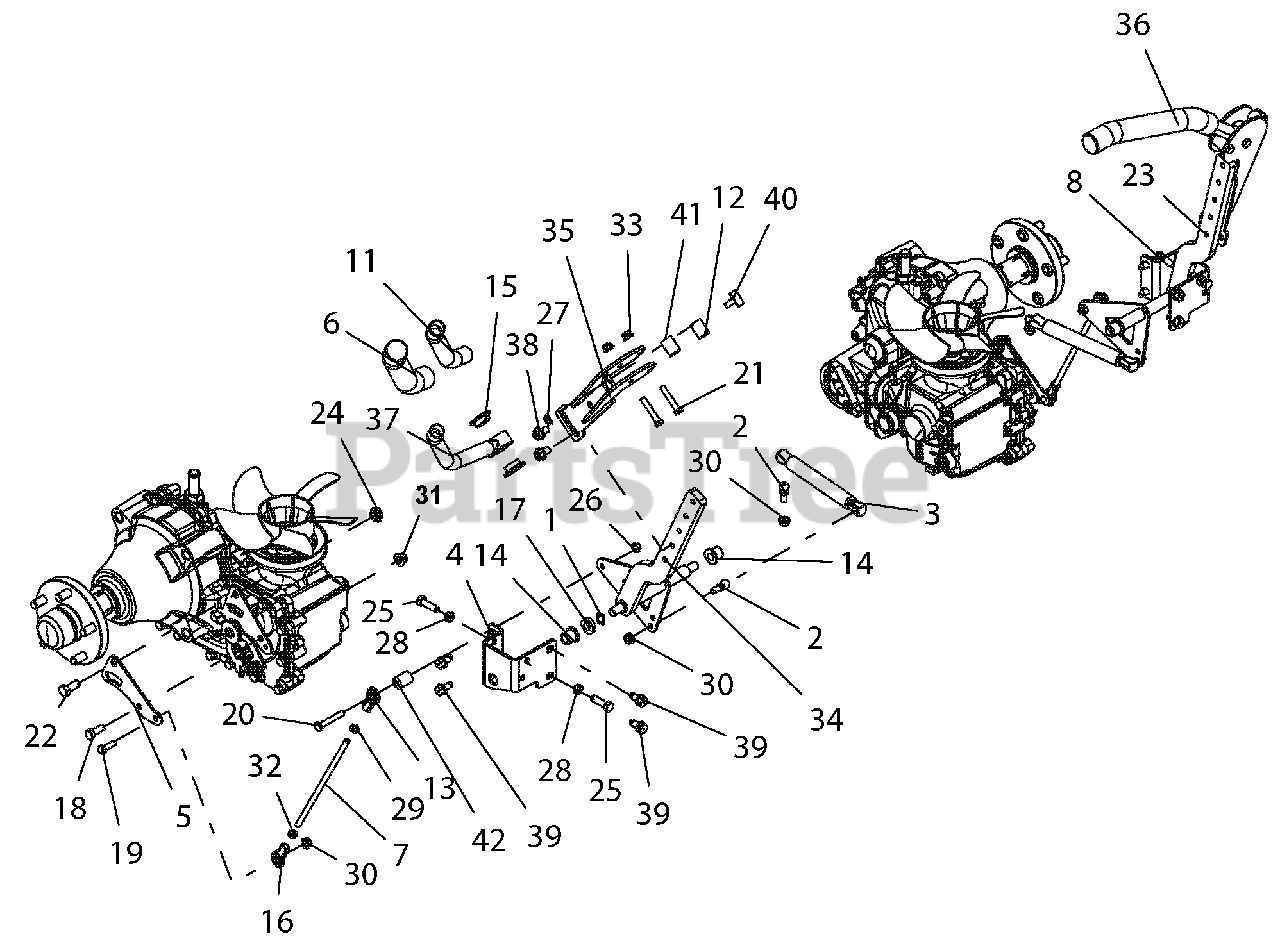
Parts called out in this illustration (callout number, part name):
1	WAVE WASHER .531X.781X.125 FH
2	STUD-BALL
3	DAMPER,
4	BRKT, RH CONTROL STOP
5	BRKT., CONTROL MTG-BLACK
6	GRIP, HANDLEBAR
7	ROD, STEERING
8	BRKT, LH CONTROL STOP
11	TUBE, .88ID X 1.00OD X 10.25
12	BSHG, ECCENTRIC .328 X .750 X .970
13	ALIGNABALL, 5/16 RH THREAD
14	BHSG-FLG .500X.750X.750X.125
15	BSHG, FLANGE .762 X 1.48 X .44 NYLON
16	ALIGNABALL, 5/16 LH THREAD
18	BLT-HEX .38-16X1.00 GR5 YWZC
19	BLT-HEX .31-18X1.00 GR5 YWZC
20	BLT-HEX .31-18X2.00 GR5 YWZC
21	BLT-HEX .31-18X1.75 GR5 YWZC
22	BLT-HEX .44-14X1.00 GR5 YWZC
23	WLDMT, LH LOWER CONTROL ARM
24	NUT-LK-NYL-FLG .44-14 YWZC
25	BLT-HEX .38-16X1.25 GR5 YWZC
26	NUT-LK-CTR .31-18 YWZC
27	@NUT-SPNLK-FLG .312-18 YWZC
28	NUT, JAM .375-16 YWZC
29	NUT-JAM
30	NUT, LK-TOP-FLG .312-18 YWZC
31	NUT-LK-NYL-FLG .38-16 YWZC
32	NUT, JAM -LH .31-24 YWZC
33	NUT-LK-NYL-FLG .31-18 YWZC
34	WLDMT, RH LOWER CONTROL ARM
35	WLDMT, ADJUSTABLE STEERING HANDLE MOUNT (BLACK)
36	WLDMT, LH HANDLE
37	WLDMT, RH HANDLE
38	BLT-SERHFWH .38-16X.62 YWZC
39	SCR-TAP .38-16X.75 HWH TR YWZ
40	BUMPER, RUBBER
41	SPACER, .328 X .76 X 1.01
42	ECCENTRIC
